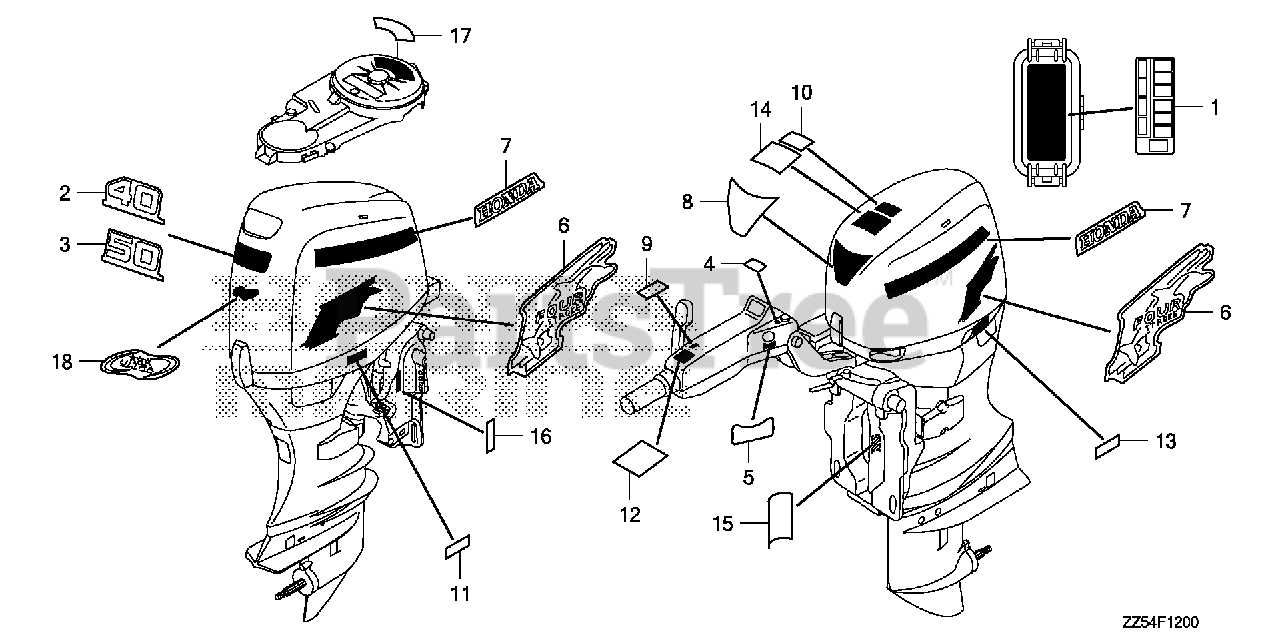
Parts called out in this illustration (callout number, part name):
1	LABEL, FUSE
2	MARK, RR. (40)
4	MARK, EMERGENCY SWITCH INDICATION
4	MARK, EMERGENCY SWITCH INDICATION (EU)
5	MARK, STARTER (ENGLISH)
6	MARK, SIDE
7	MARK, SIDE STRIPE
8	MARK, FR. EMBLEM (40)
9	MARK, CHANGE (JAPANESE/ENGLISH)
11	LABEL, OIL CAUTION (ENGLISH)
12	MARK, THROTTLE (ENGLISH)
13	LABEL, STORING CAUTION (ENGLISH)
14	LABEL, CAUTION OPERATOR (ENGLISH)
15	LABEL, ASSIST TILT CAUTION (ENGLISH)
16	MARK, ASSIST LEVER (ENGLISH)
17	MARK, EMERGENCY START (ENGLISH)
